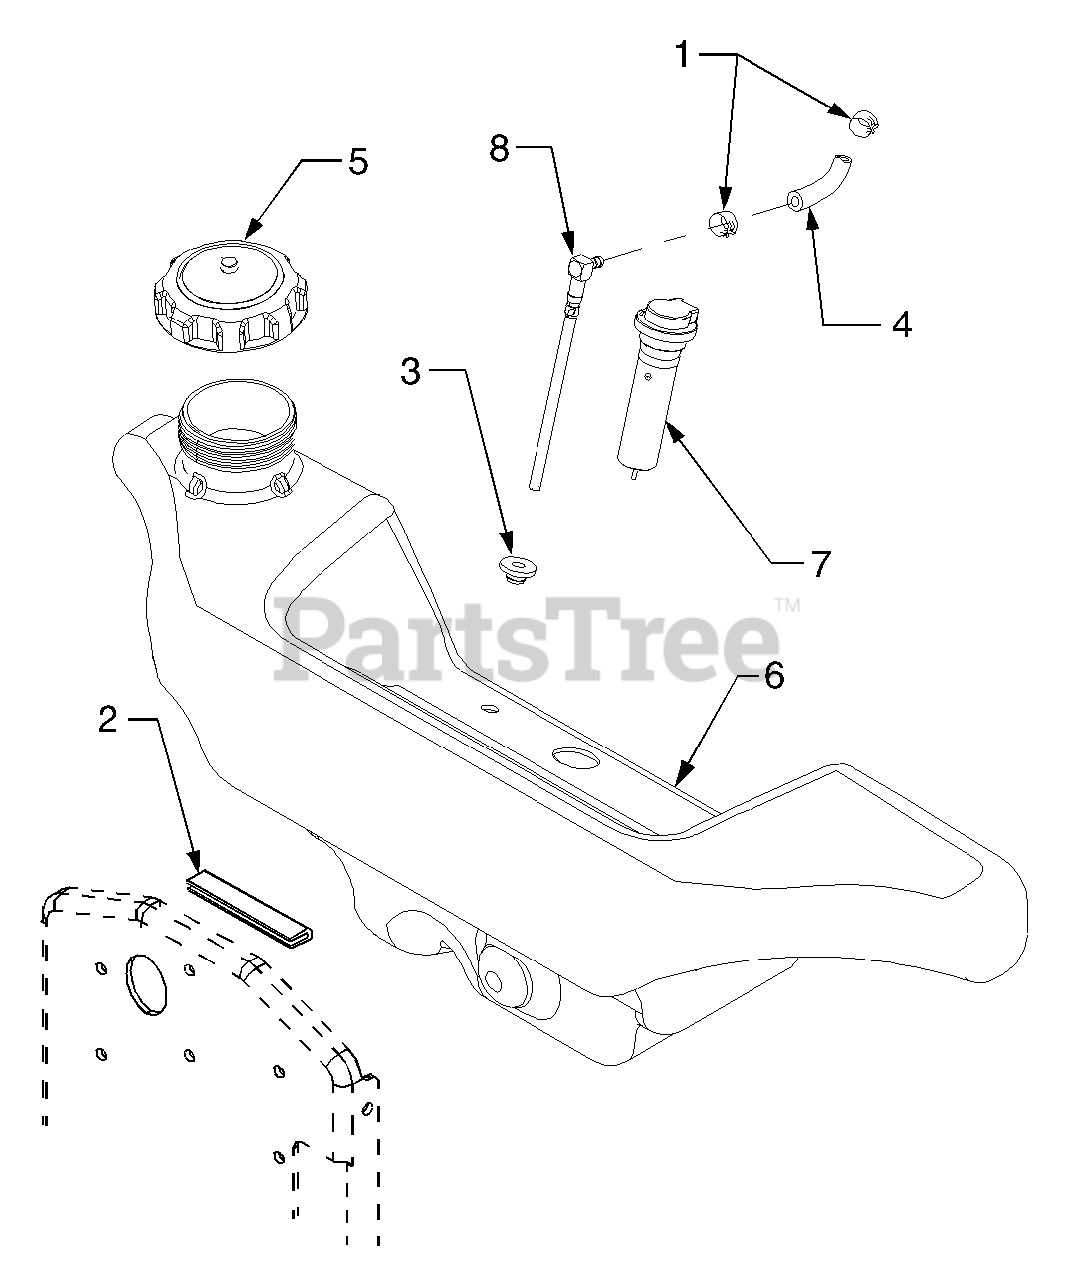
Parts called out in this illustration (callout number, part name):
1	Clamp, Hose
2	Trim, Tank Protector
3	Bushing, Rubber
4	Fuel Line
5	Cap, Fuel
6	Tank Assembly, Fuel
7	Sensor, Low Fuel
7	Grommet
8	Fitting, Fuel Pickup
